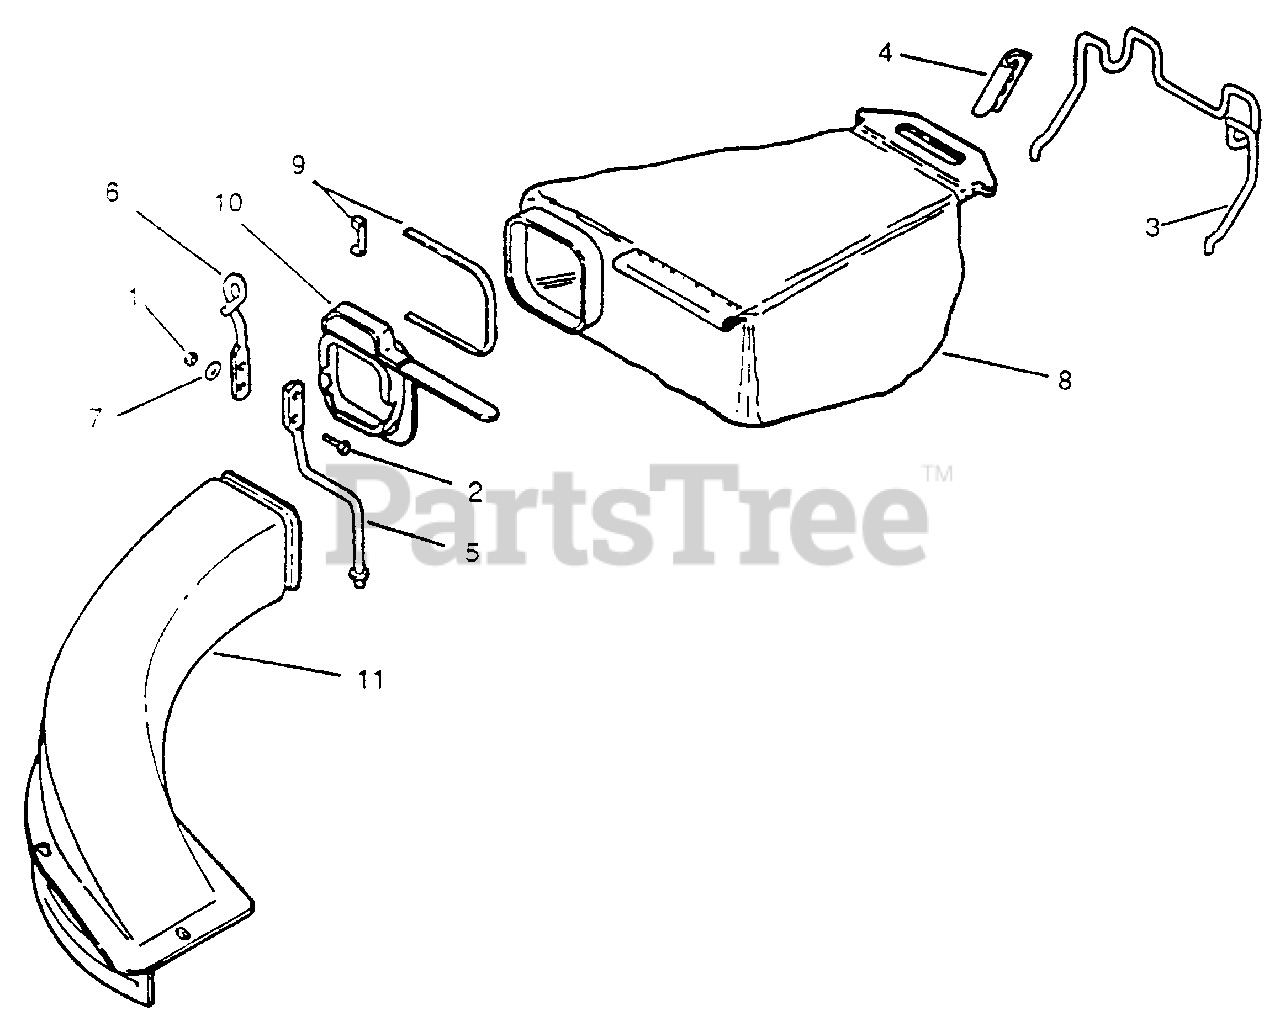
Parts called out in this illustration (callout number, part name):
1	Locknut
2	Screw
3	Wide Hanger
4	Hanger Clamp
5	Chute Support
6	Rope Guide
7	Washer
8	Bag Assembly (Inc. 9)
9	Strap & Lock Assembly
10	Adaptor Assembly
11	Chute
45	Decal-Fuel Mix
